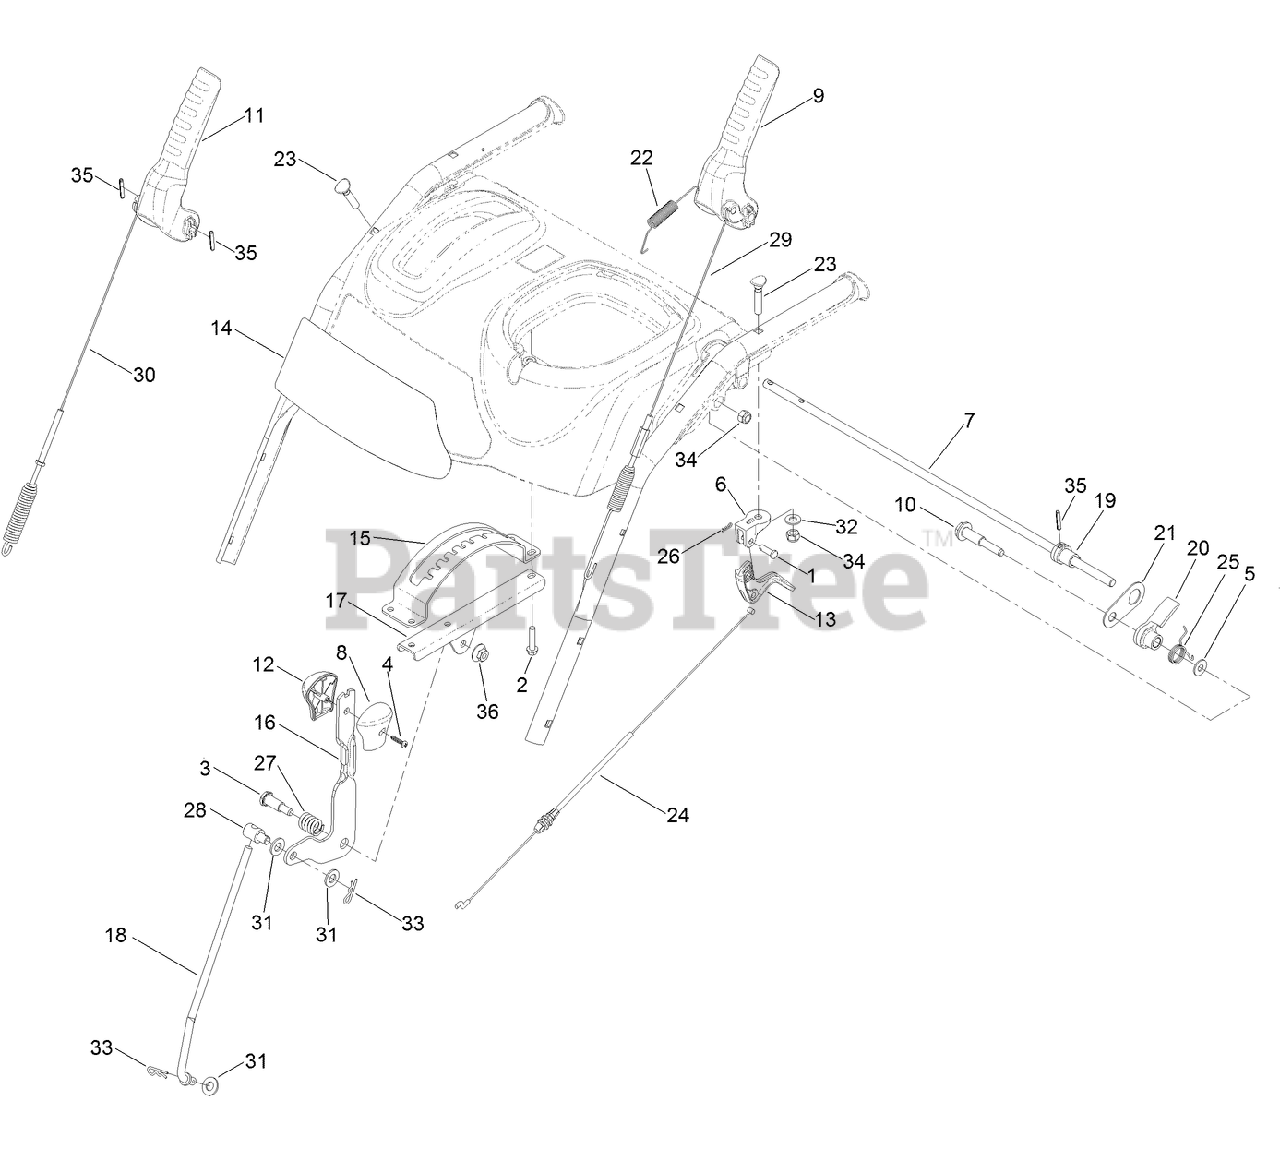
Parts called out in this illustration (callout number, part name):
1	PIN-CLEVIS
2	SCREW-PLASTITE
3	SCREW-SHOULDER
4	SCREW-PPH
5	WASHER-FLAT
6	MOUNT-LEVER, CLUTCH
7	ROD-LOCKOUT
8	KNOB-SHIFT, LH
9	LEVER-TRACTION
11	LEVER-AUGER
12	KNOB-SHIFT, RH
13	LEVER-CLUTCH
15	GUIDE-SELECTOR, SPEED
16	SELECTOR-SPEED
17	BRACKET-SELECTOR, SPEED
19	CAM-LOCKOUT
20	LATCH-LOCKOUT
21	LINK-LOCKOUT
22	SPRING-TENSION
23	SCREW-HANDLE
24	CABLE-CLUTCH
25	SPRING-TORSION
26	PIN-HAIR
28	TRUNNION-ROD
29	CABLE-TRACTION
30	CABLE-AUGER
31	WASHER-FLAT
32	WASHER-FLAT
34	NUT-LOCK, NI
35	PIN-SPRING
36	NUT-HF
